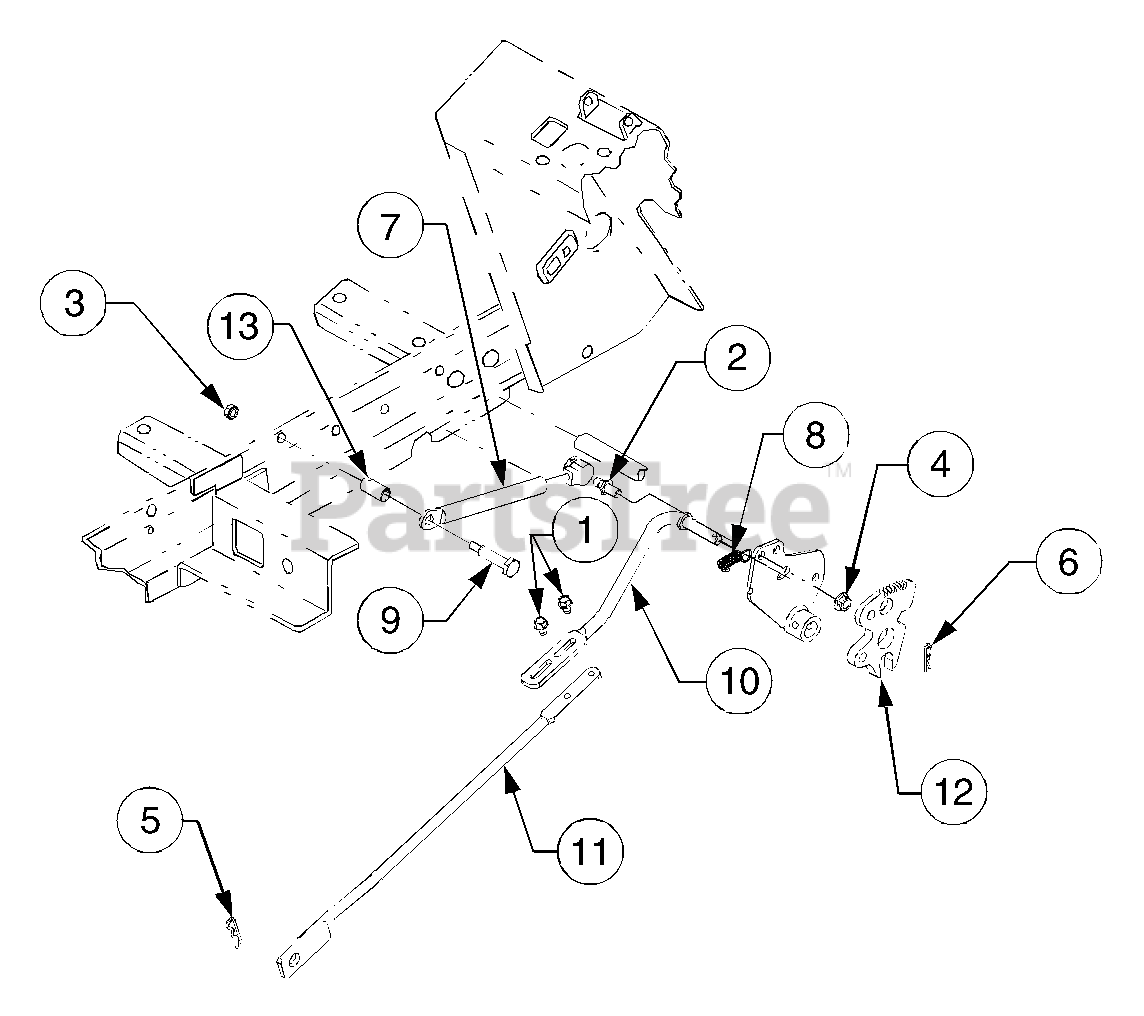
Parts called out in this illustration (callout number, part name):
1	Screw, Hex Wsh Hd Tapp, 1/4-20 x .75
2	Screw, Ball, 5/16-18 x.56
3	Nut, Hex Sems, 1/4-20
4	Nut, Hex Flange Lock, 1/4-20
5	Pin, Internal Cotter
6	Pin, Internal Cotter
7	Cylinder, Damper
8	Spring, Extension, 3/8 OD x 1.44
9	Bolt, Shoulder, .374 Dia x 1.375
10	Rod, Front Control
11	Rod, Rear Hydro Control
12	Plate, Cruise
13	Spacer, Split Tubing, .375 ID x 1.04
